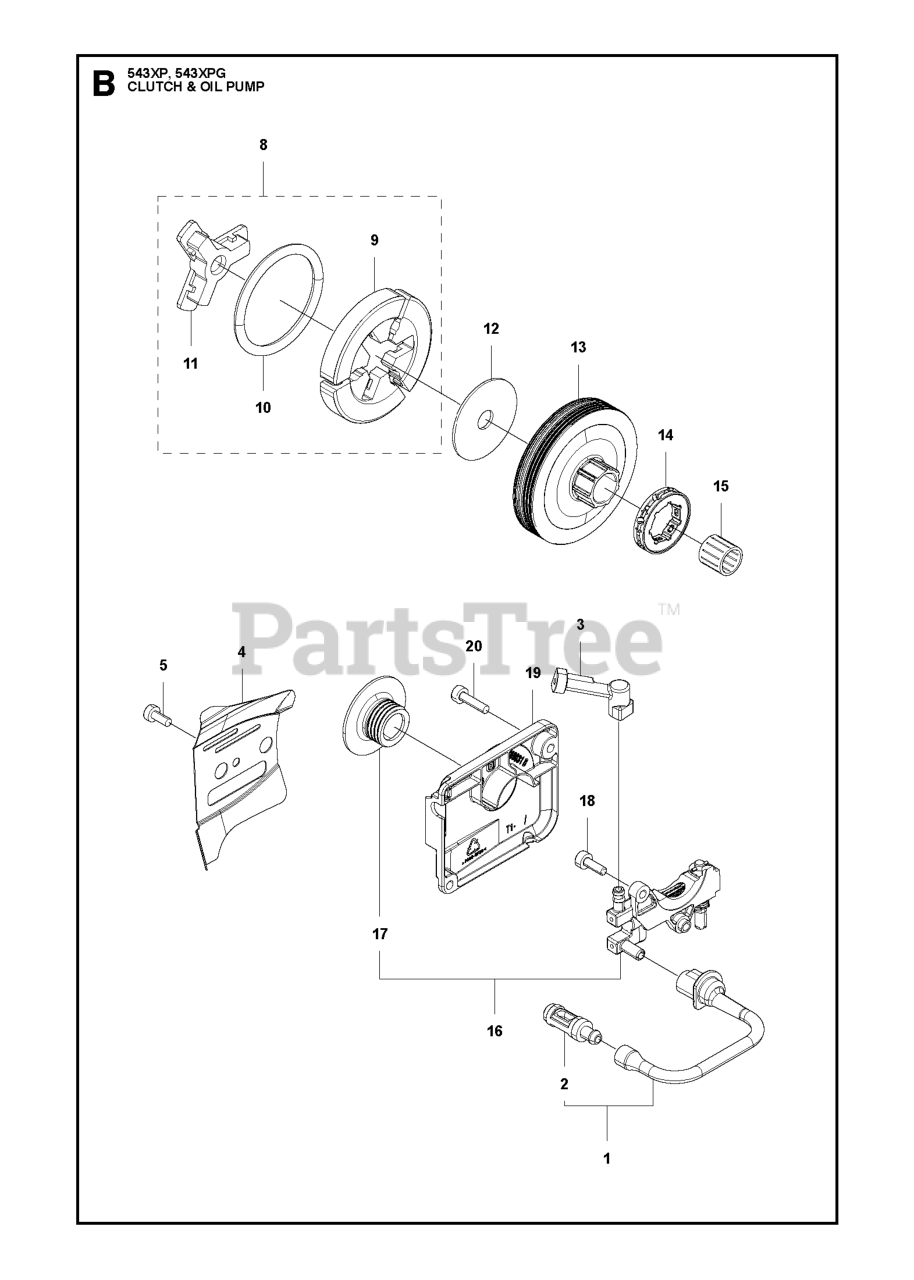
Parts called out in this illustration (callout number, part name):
2	FILTER
4	BAR MOUNT PLATE
5	SCREW
8	CLTUCH ASSY
10	CLUTCH SPRING
13	DRUM
16	OIL PUMP SET (RPLS 848C806711)
18	BOLT
19	PUMP COVER
20	BOLT M4 X 12 T27
